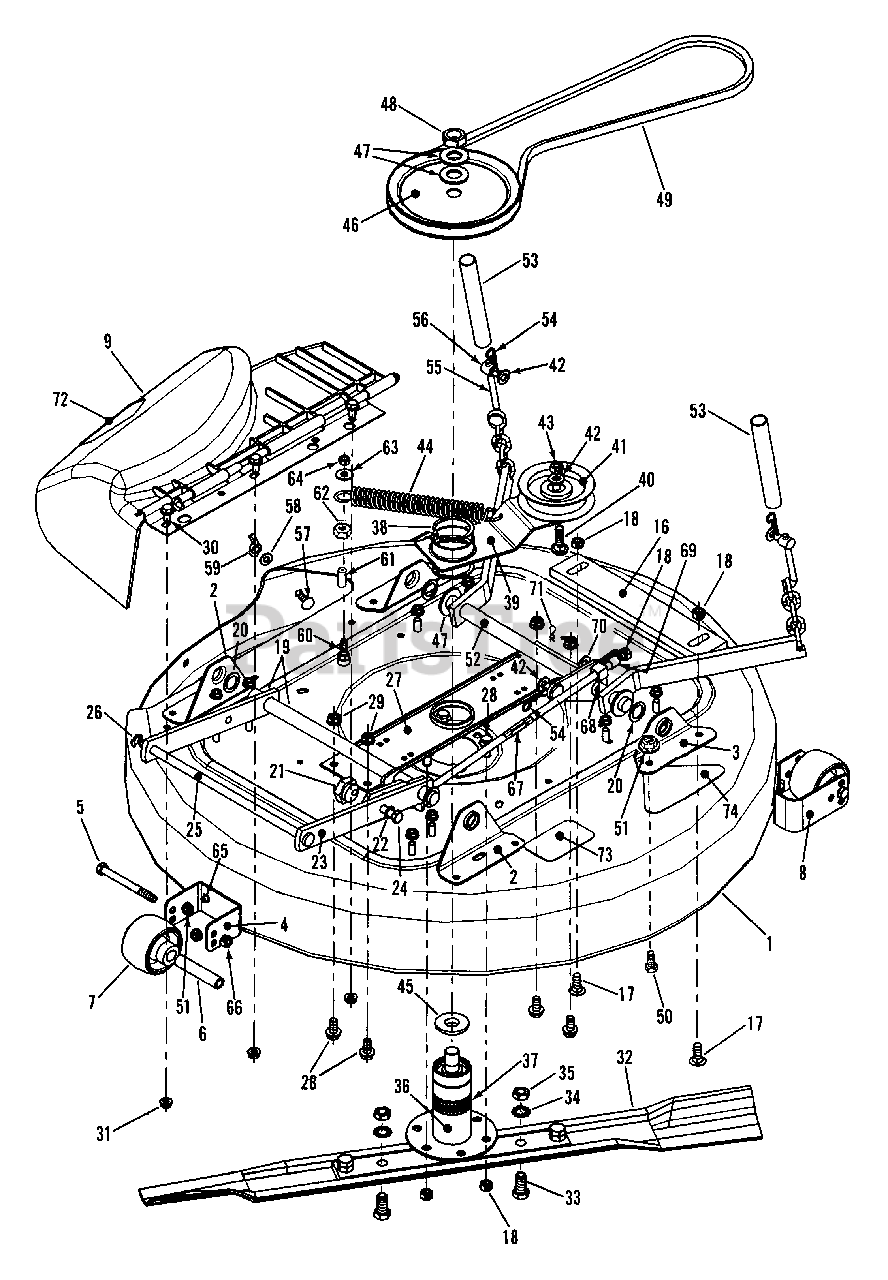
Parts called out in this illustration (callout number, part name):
1	DECK, 33'
2	BRACKET, Deck Lift Slotted
3	BRACKET, Deck Lift
4	BRACKET, Anti-Scalp Adj. Front
5	SCREW, 3/8-24 x 3/4" H.H. Cap
6	SPACER, 3" Long
7	WHEEL, Gage
8	BRACKET, Anti-Scalp Adj.Side
9	ASY,Chute 28" & 33" Discharge
16	BAR, Weight Rear
17	BOLT, 3/8-16 x 1" Carriage
18	NUT, 3/8-16 Hex Lock
19	ARM, Front Lift
20	WASHER, 3/4"
21	ECCENTRIC, Leveling
22	WASHER, 3/8" Internal Tooth Lock
23	ARM, Front Lift
24	SCREW, 3/8-24 x 1-1/4" H. H. Cap
25	ROD, Deck Support
26	RING, 7/16" Snap
27	BRACE, Spindle
28	BOLT, 3/8-16 x 3/4" Hex Flange Lock, Grade 5
29	NUT, 3/8-16 Hex Flange Lock
30	BOLT, 5/16-18 x 5/8" Hex Flange Lock, Grade 5
31	NUT, 5/16-18 Hex Flange Lock Grade 5
32	BLADE, 33" High Lift
33	SCREW, 1/2-20 x 1" H. H. Cap
34	WASHER, 1/2" Internal Tooth Lock
35	NUT, 1/2-20 Hex Jam
36	ASSEMBLY, Spindle
37	RING, 2" Tolerance
38	RING, 2" External Retaining
39	ARM, Idler
40	BOLT, 3/8-16 x 2" Carriage
41	IDLER, 4" O.D. Flat
42	WASHER, 3/8" Flat
43	NUT, 3/8-16 Hex Lock
44	SPRING, External
45	WASHER, Spindle
46	PULLEY, Spindle
47	WASHER, 25/32" Flat
48	NUT, 3/4-16 Hex Jam
49	BELT, HA 33" Deck
50	BOLT, 5/16-18 x 3/4" Hex Flange Lock
51	NUT, 5/16-18 H.F. Lock
52	ARM, Rear Lift
53	COVER, Chain
54	PIN, 3/32 x 1-1/2" Hair
55	ADJUSTER, Chain
56	SWIVEL, Adjustable
57	BOLT, 5/16-18 x 3/4" Carriage Grade 5
58	WASHER, 11/32" Grade 5
59	NUT, 5/16-18 Wing
60	BOLT, 5/16-18 x 1-1/2" Hex Flange Lock
61	SPACER, 11/32"
62	NUT, 5/16-18 Hex Lock
63	WASHER, 3/8" Flat
64	NUT, 5/16-18 Hex Lock
65	BOLT, 5/16-18 x 1/2" Carriage
66	NUT, 3/8-24 Hex Lock
67	ROD, Cutting Deck Timing
68	SWIVEL, Brake Link PM
69	SPACER, 25/64"
70	WASHER, 3/8"
71	PIN, Hair
72	DECAL, Caution
73	DECAL, Caution
74	DECAL, Hi-Vac
